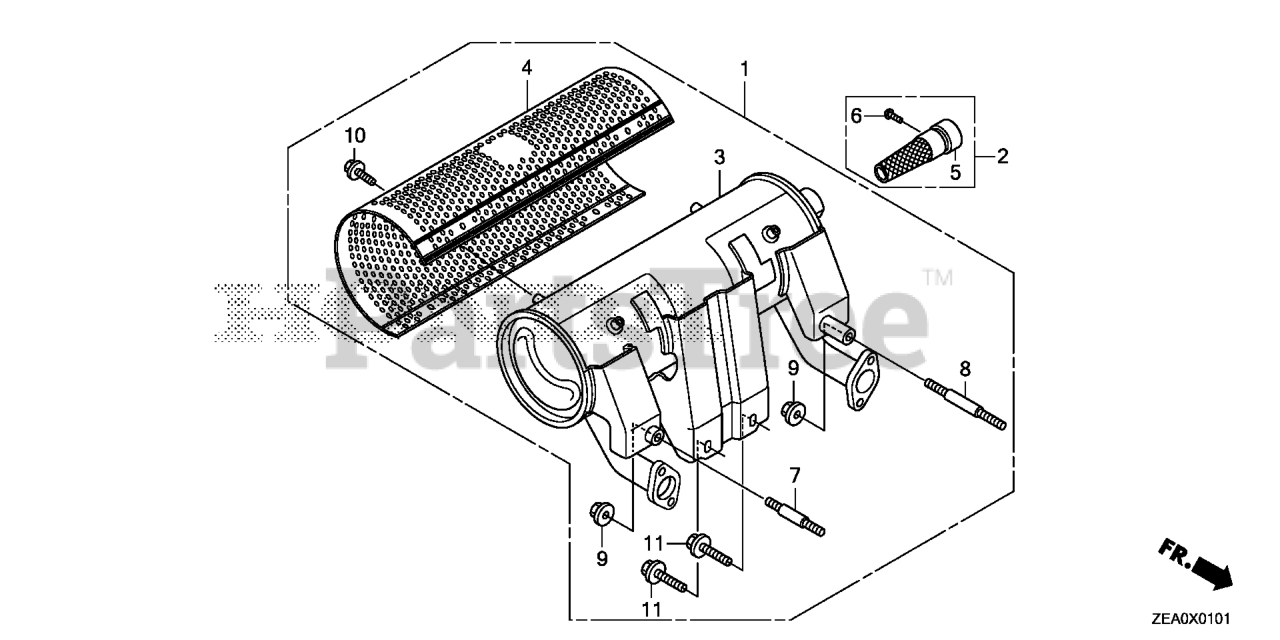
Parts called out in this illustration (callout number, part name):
1	MUFFLER KIT (HIGH-L)
2	ARRESTER KIT (HIGH)
3	MUFFLER (HIGH-L)
4	PROTECTOR, MUFFLER (HIGH) (FUTABA)
5	ARRESTER, SPARK
6	SCREW, TAPPING (5X8) (FOR SILVER MUFFLER)
7	BOLT, STUD (8X45)
8	BOLT, STUD (8X60)
9	NUT, FLANGE (8MM)
10	BOLT, FLANGE (6X8)
11	BOLT, FLANGE (8X20) Use up to Engine SN 1609606.
